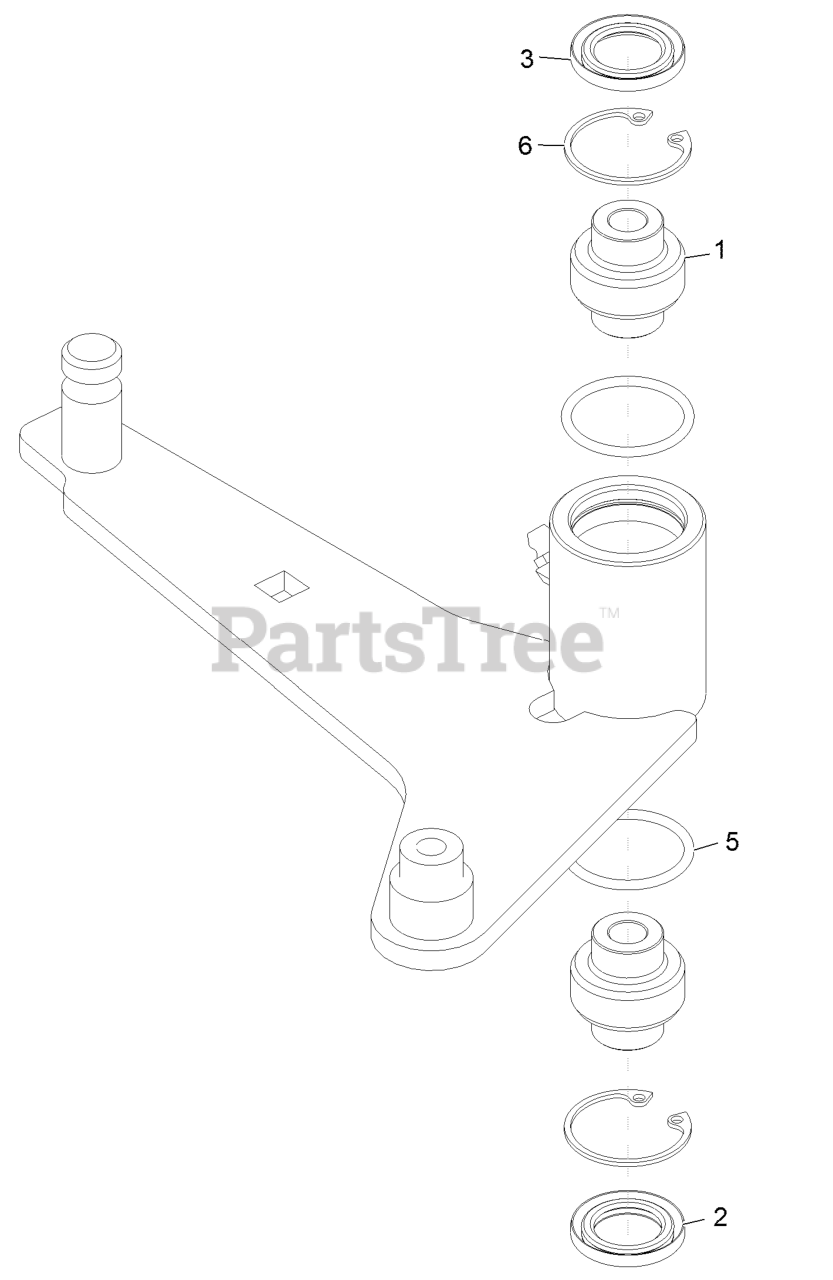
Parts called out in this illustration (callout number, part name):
1	BEARING-SPHERICAL
2	SEAL-LIP, DOUBLE
3	SEAL-LIP, SINGLE
6	RING-SNAP
